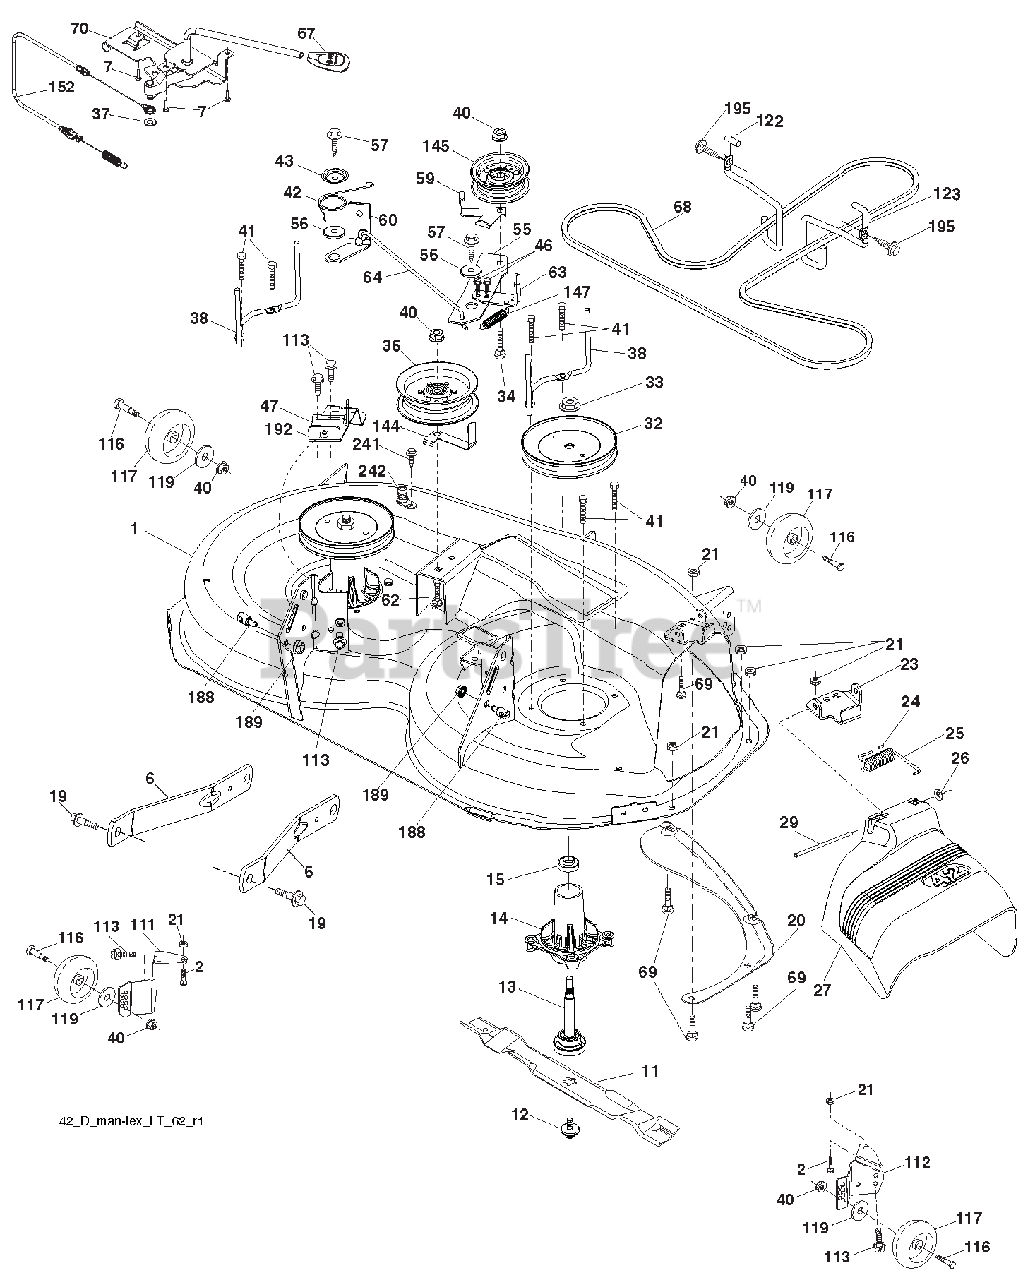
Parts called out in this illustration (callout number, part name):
1	DECK.WELDMENT.42"
6	ARM.SUSPENSION.MOWER.REAR.LD
11	BLADE.MOWER.42"HI LIFT PREMIUM
12	SCREW 7/16-20 X 1
13	SHAFT ASM
14	HOUSING.MANDREL.4PT.SERVICE
15	BEARING
19	BOLT.SHOULDER
20	BAFFLE.VORTEX.42.STD/HEAVY DTY
21	Nut, Hex, Crownlock 5/16-18
23	BRACKET.DEFLECTOR.38/42"2005
24	CAP.SLEEVE..80X.112.BLK.MOWER
25	SPRING.TORSION.DFL.38/42/46.GR
26	NUT.PUSH.PHOS.& OIL
27	SHIELD.DEFLECTOR.
29	ROD.HINGE.42/46"
32	PULLEY.MANDREL.5.438 PD.42"
32	MANDREL ASM
33	NUT.FLANGE.LOCK.TOP
34	BOLT.CARR.SH.3/8-16X1-1/2.GR5
36	PULLEY.IDLER.4.50.RAW
37	WASHER.13/32 X 13/16 X 16 GA.
38	KEEPER.BELT.MANDREL.PULLEY
40	Nut, Hex, Flangelock 3/8-16
41	HEX HEAD BOLT
42	SPRING.TORSION.BRAKE
43	SPRING.TORSION.RETAINER
46	SCREW.THD.ROLL.1/4-20 X 5/8
47	BRACKET.CLUTCH.CABLE
55	IDLER.ARM
56	SPACER.RETAINER
57	SCREW.3/8-16X1.SMGML.TAP/R.BLK
59	GUARD.TUV.IDLER
60	ARM.BRAKE.MOWER.42"
62	BOLT.RD.HD.SQ.NK.3/8-16UNC X 2
63	ARM.BRAKE.MOWER
64	LINKAGE.BRAKE
67	HANDLE.CLUTCH.CABLE.LT TEX.428
68	BELT.DRIVE.100.97"
69	BOLT.RDHD.SQNK.5/16-18 X 5/8
70	CLUTCH.ASM.MANUAL
111	BRACKET WHEEL GAUGE LH
112	BRACKET WHEEL GAUGE RH
113	BOLT.5/16-18HEX.WHS.HD.LCKSERR
116	BOLD SHLD "A" 2.41 "B" 1.66
117	WHEEL.GAGE.HALF.SPOKED
119	Washer 3/8 x 7/8 x 14 Ga.
122	KEEPER.BELT.ENGINE.LH.LT.TEX
123	KEEPER.BELT.ENGINE.RH.LT.TEX
144	KEEPER.BELT.MOWER
145	PULLEY.IDLER 48"PRIMARY
147	SPRING.RETURN
152	CABLE.CLUTCH.MANUAL
188	STUD.FASTNER.W/'D'ANTI-ROTATIO
189	Nut, Lock Hex Flange 5/16-18 u
192	BRACKET.BRAKE.STAND.LH
195	SCREW.HEXWSH THDR3/8-16X3/4.BL
242	PORT WASHOUT
243	COUPLING QUICK CONNECT
244	DECK.REPLACEMENT
